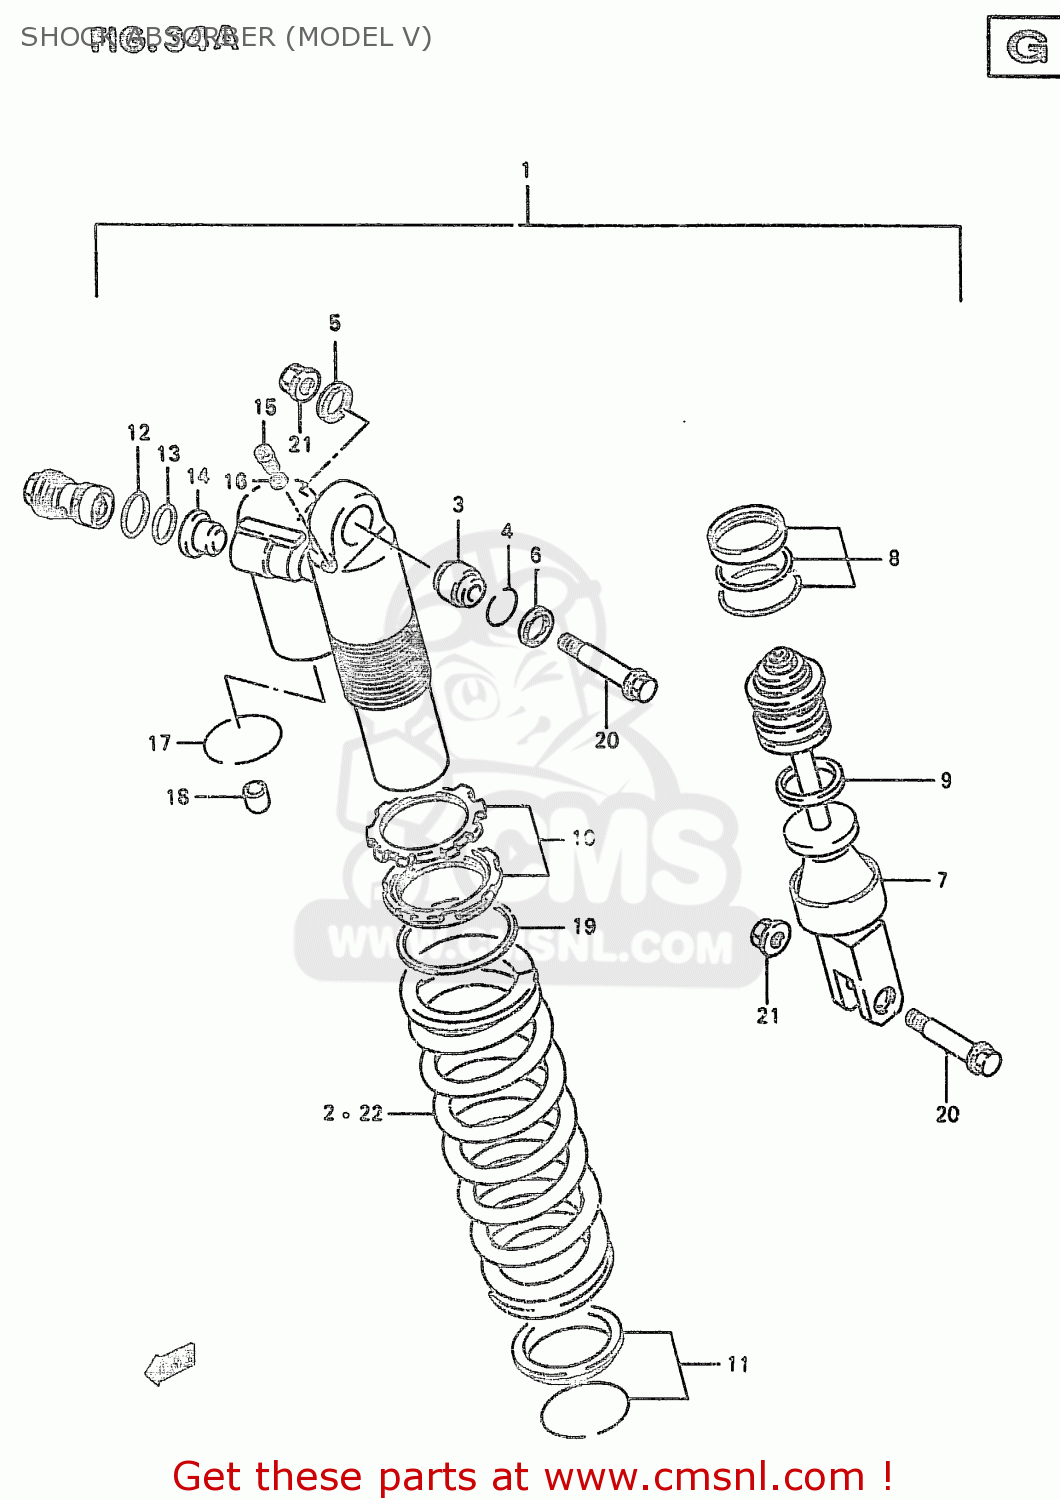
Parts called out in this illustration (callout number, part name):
1	ABSORBER ASSY, REAR SHOCK (PURPLE)
2	SPRING,REAR (K=5.20)
3	BEARING,RR SHOCK ABSORBER
4	RING,STOPPER
5	SEAL,DUST UPR,R
6	SEAL,DUST UPR,L
7	ROD,PISTON
8	O RINR SET
9	RING,STOPPER
10	ADJUSTER SET,SHOCK ABSORBER
11	SPRING SEAT SET,SHOCK ABSORBER
12	O RING
13	O RING,CTR BOLT UPR
14	COLLAR,ORIFICE
15	BOLT
16	GASKET,DRAIN,PLUG (NAS)
17	RING,STOPPER
18	CAP
19	SEAT,SPRING
20	BOLT(10X47.5)
21	NUT
22	SPRING,RR(K=4.8)
